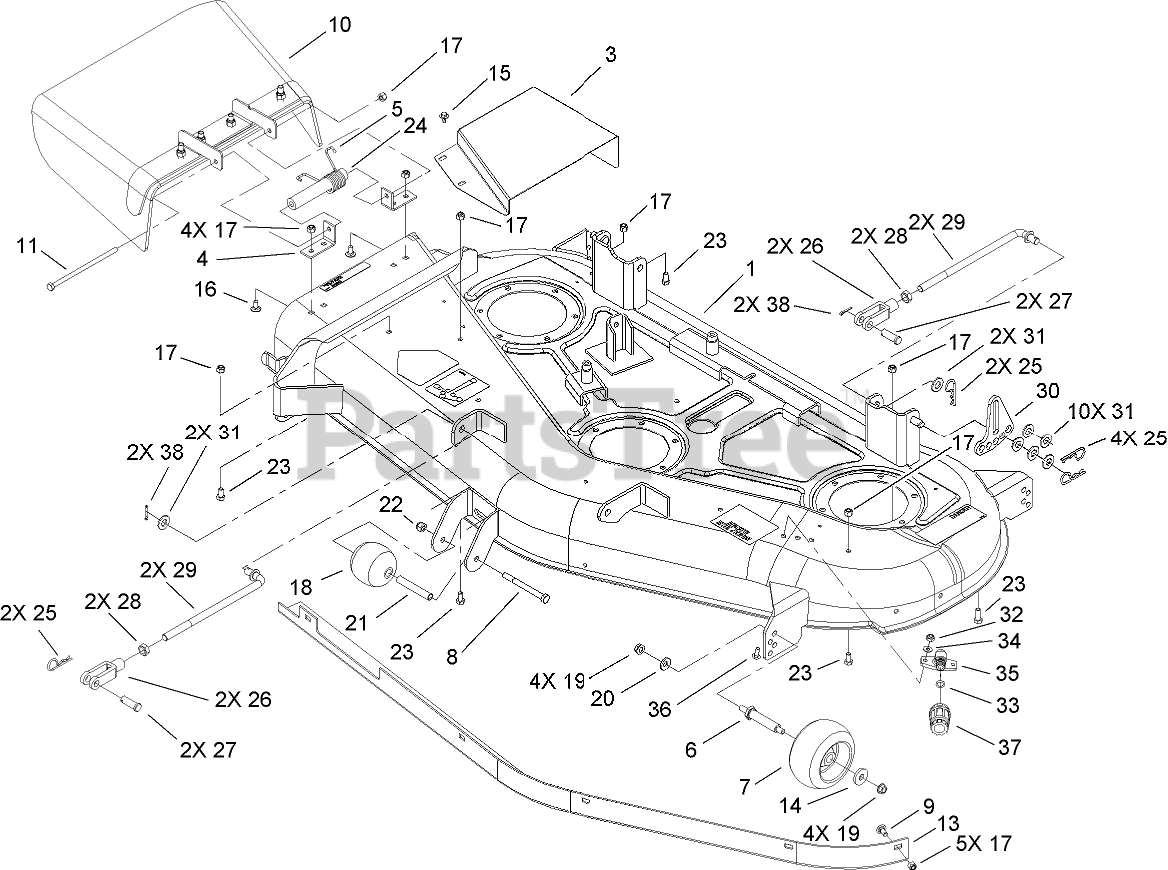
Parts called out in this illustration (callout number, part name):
1	52 INCH DECK ASM
3	COVER-BELT, RH
4	BRACKET-PIVOT, DEFLECTOR
5	SPRING-TORSION
6	SPACER
7	ROLLER-SCALP, ANTI
8	SCREW-HH
9	SCREW-CARR
10	DEFLECTOR ASM
11	BOLT-HH
14	WASHER
15	SCREW-HHFTF
16	SCREW-CARR
17	NUT-LOCK, NI
18	ROLLER
19	NUT-HHF, WHIZ
20	WASHER-BELLEVILLE
21	TUBE-SPACER, WHEEL
22	NUT-LOCK, NI
23	SCREW-HH
24	SPACER-DEFLECTOR
25	PIN-COTTER
26	CLEVIS
27	PIN-CLEVIS
28	NUT-JAM
29	ROD-TRUNION
30	LINK-HOC, ADJUSTING
31	WASHER-FLAT
32	NUT-LOCK, NI
33	O-RING
34	WASHER-FLAT
35	FITTING-WASHOUT
36	BOLT-CARR
37	CONNECTOR-HOSE
38	PIN-COTTER
